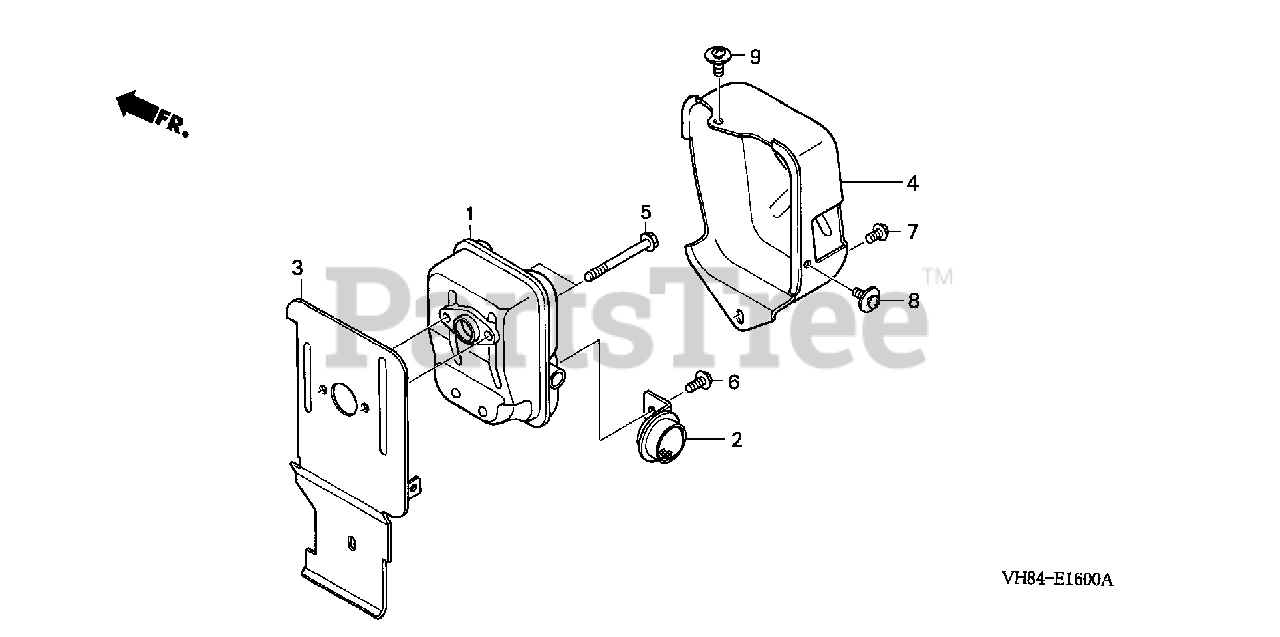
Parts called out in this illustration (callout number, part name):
1	MUFFLER
2	ARRESTER, SPARK
3	GUIDE, AIR EX.
4	COVER, TOP (INNER)
5	BOLT, FLANGE (5X50)
6	SCREW, TAPPING (4X6)
7	SCREW-WASHER (5X8)
8	SCREW-WASHER (5X10)
9	SCREW-WASHER (5X16)
